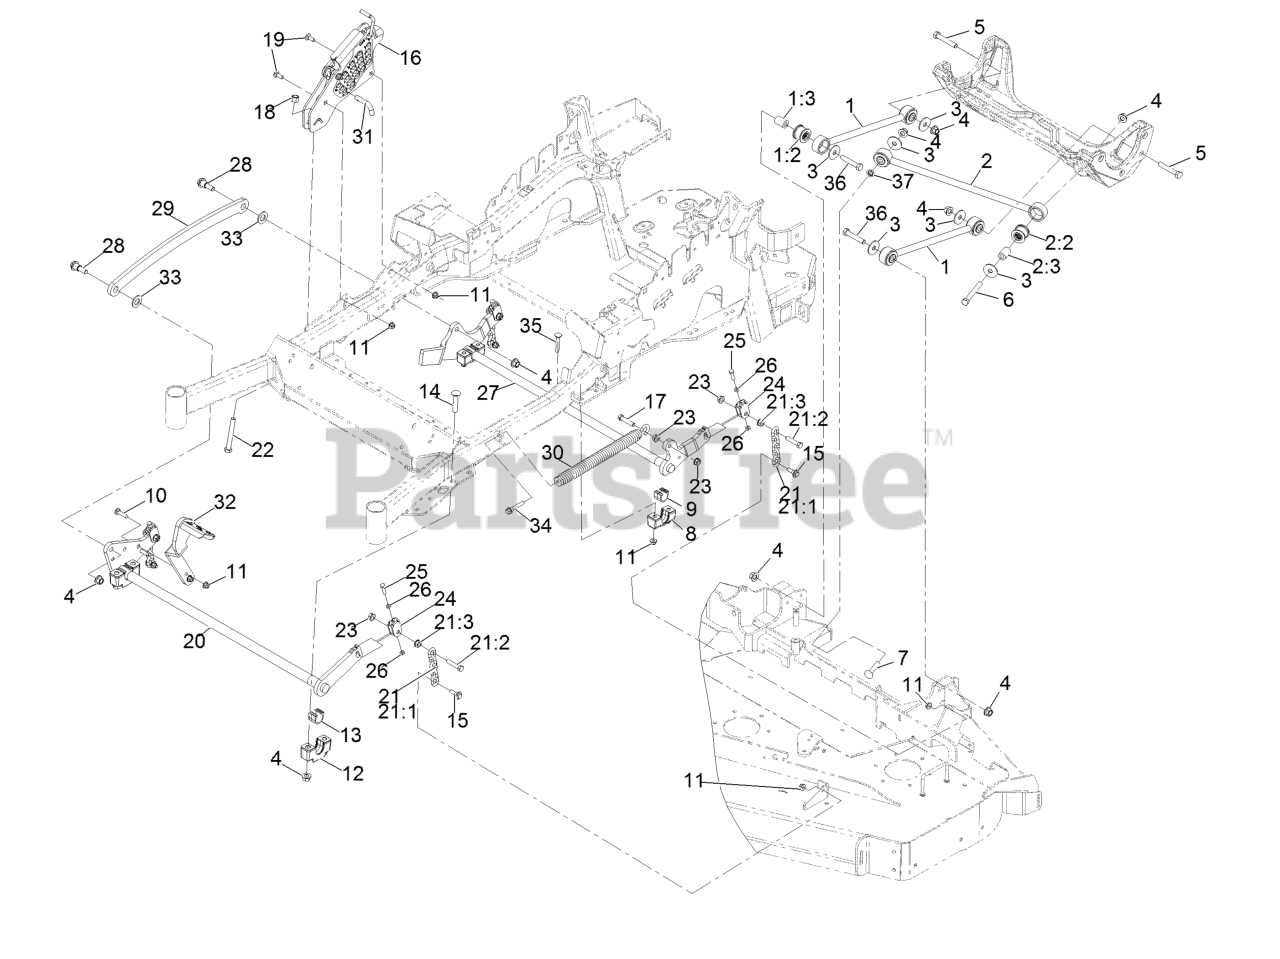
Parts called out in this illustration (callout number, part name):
1	Deck Strut ASM
1:2	Bushing-Suspension, Rubber
2	Panhard Rod ASM
2:2	Bushing-Suspension, Rubber
4	Nut-Lock 1/2-13
5	Screw-HH 1/2-13 X 3
6	Screw-HH 1/2-13 X 4
7	Bolt-Carriage 1/2-13 X 2 1/2
8	Support-Cross Shaft, Bearing Rear
9	Bearing-Cross Shaft, Rear
10	Bolt-Carriage 3/8-16 X 1 1/2
11	Nut-Nyloc 3/8-16 Flg
12	Support-Cross Shaft, Bearing
13	Bearing-Cross Shaft, Front
14	Bolt-Carriage 1/2-13 X 2 1/2 Spl Neck
15	Screw-Hex Flange 3/8-16 X .80
16	HOC ASM
17	Screw-HH 7/16-14 X 2
18	Nut-Nyloc 1/2-13
19	Bolt-Carriage 3/8-16 X 1
20	Decklift-Front
21	Deck Lift Chain ASM
21:1	Chain-Lift, Deck
21:2	Screw-HH 7/16-14 X 2
21:3	Nut-Whizlock 7/16-14
22	Bolt-HH 1/2-13 X 4 Tap
23	Nut-Whizlock 7/16-14
24	Yoke-Adjust, Deck
25	Screw-HH 5/16-18 X 1 1/4
26	Nut-Jam 5/16-18
27	Lift-Deck, Rear
28	Screw-Shoulder HHF 1/2-13 X 1.12
29	Link-Lift, Deck
30	Spring-Extension
31	Pin-HOC
32	Lever-Foot
33	Washer-3/4 SAE
34	Screw-Shcs 3/8-16 X 2.212
35	Bolt-Carriage 3/8-16 X 2 1/4
36	Screw-HH 1/2-13 X 2 3/4
37	Nut-Push
